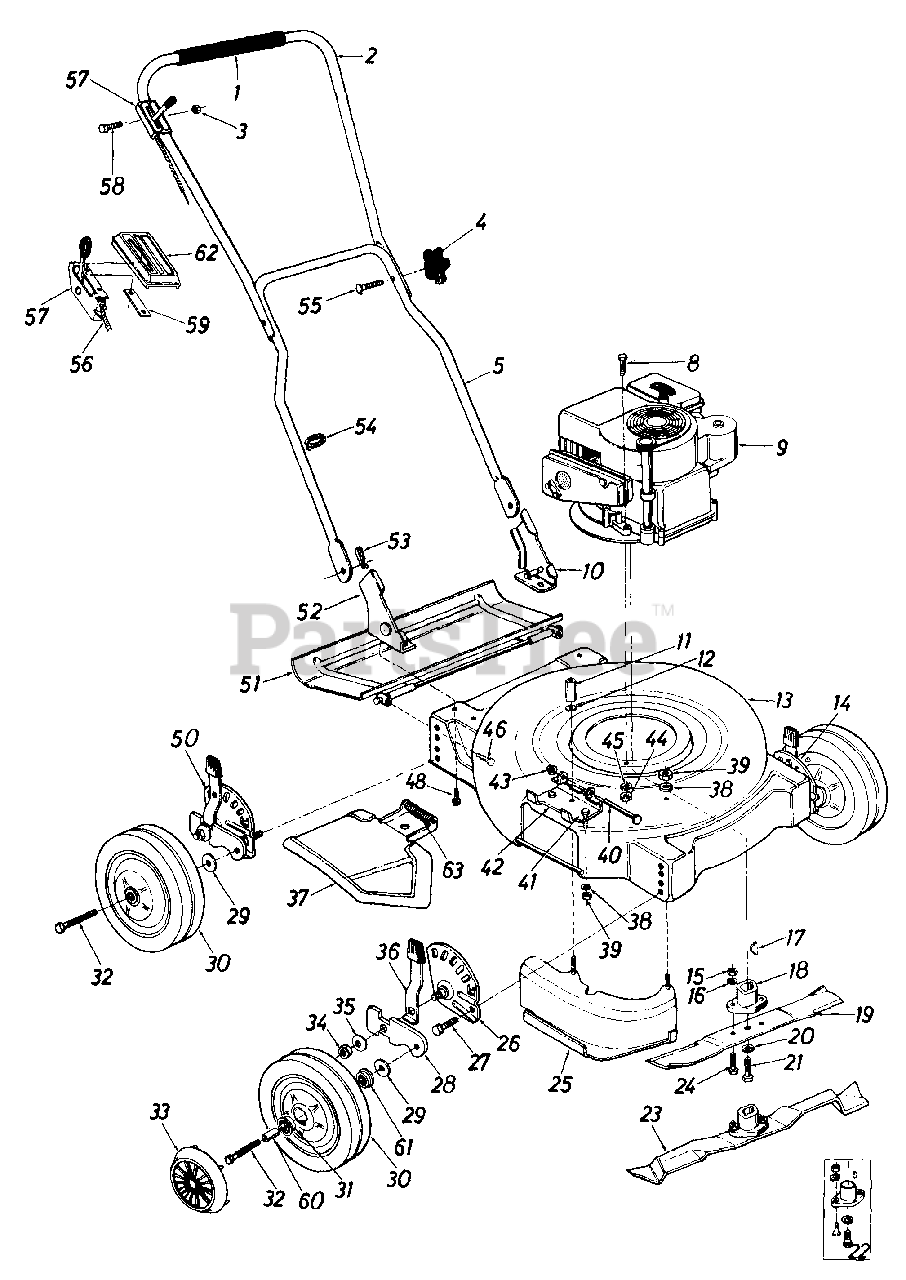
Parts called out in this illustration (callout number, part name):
2	Upper Handle
3	Hex Cent. L-Nut 1/4-20 Thd.
4	Hand Knob
5	Lower Handle
8	Hex Bolt 5/16-24 x 1.50" Lg.
9	Engine
10	Handle Mounting Brkt. - L.H.
11	Hex Spacer Stop
12	L-Wash. 1/4" I.D.
13	20" Deck Ass'y.
14	Height Adj. Ass'y. w/Black Knob - L.H.
15	Hex Nut 5/16-24 Thd.
16	L-Wash. 5/16" I.D.
17	#6 Hi-Pro Key 5/32" x 5/8" Dia.
18	Blade Adapter Kit
19	20" Standard Blade
20	H Spring L-Wash. for 3/8" Scr.
21	Hex Bolt 3/8-24 x 1.50" Lg.
22	Blade Adapter Kit
23	20" Mulching Blade
24	Hex Bolt 5/16-24 x 1.00" Lg.
25	Mulching Baffle Ass'y.
26	Index Plate Ass'y. - R.H.
27	Hex Sems Scr. 3/8-16 x .62" Lg.
28	Pivot Bar
29	Bell-Wash. .40" I.D. x .88" O.D. x .06
30	Wheel Ass'y. Comp. (Steel)
31	Ball Bearing - 1/2" I.D.
32	Hex Bolt 3/8-16 x 1.75" Lg.
34	Hex Ins. Jam L-Nut 3/8-24 Thd.
35	Bell-Wash. .40 I.D. x 1.12 O.D. x .03
36	Spring Lever Ass'y. w/Knob
37	Chute Deflector Ass'y. Comp.
38	L-Wash. 1/4" I.D.
39	Hex Nut 1/4-20 Thd.
40	Pivot Pin
41	Hex Bolt 1/4-20 x .50" Lg.
42	Deflector Hinge Plate
43	Push Nut for 1/4" Rod
44	Hex Nut 5/16-24 Thd.
45	L-Wash. 5/16" I.D.
46	Hex Sems Scr. 1/4-28 x .62" Lg.
48	Hex Wash. Hd. B-Tap Scr. 5/16-18 x .50
50	Height Adj. Ass'y. w/Knob - R.H.
51	Rear Shield Ass'y. Comp.
52	Handle Mtg. Brkt. Ass'y. - R.H.
53	Intern. Cotter Pin 5/16" Dia.
54	Cable Tie
55	Curved Carriage Bolt 5/16-18 x 1.75" Lg.
56	Conduit and Wire
57	Throttle Control Ass'y. Comp.
58	Hex Bolt 1/4-20 x 1.50" Lg.
59	Speed Nut #8-32 Twin Type
61	Ball Bearing - 3/8" I.D.
62	Plastic Cover
63	Torsion Spring
